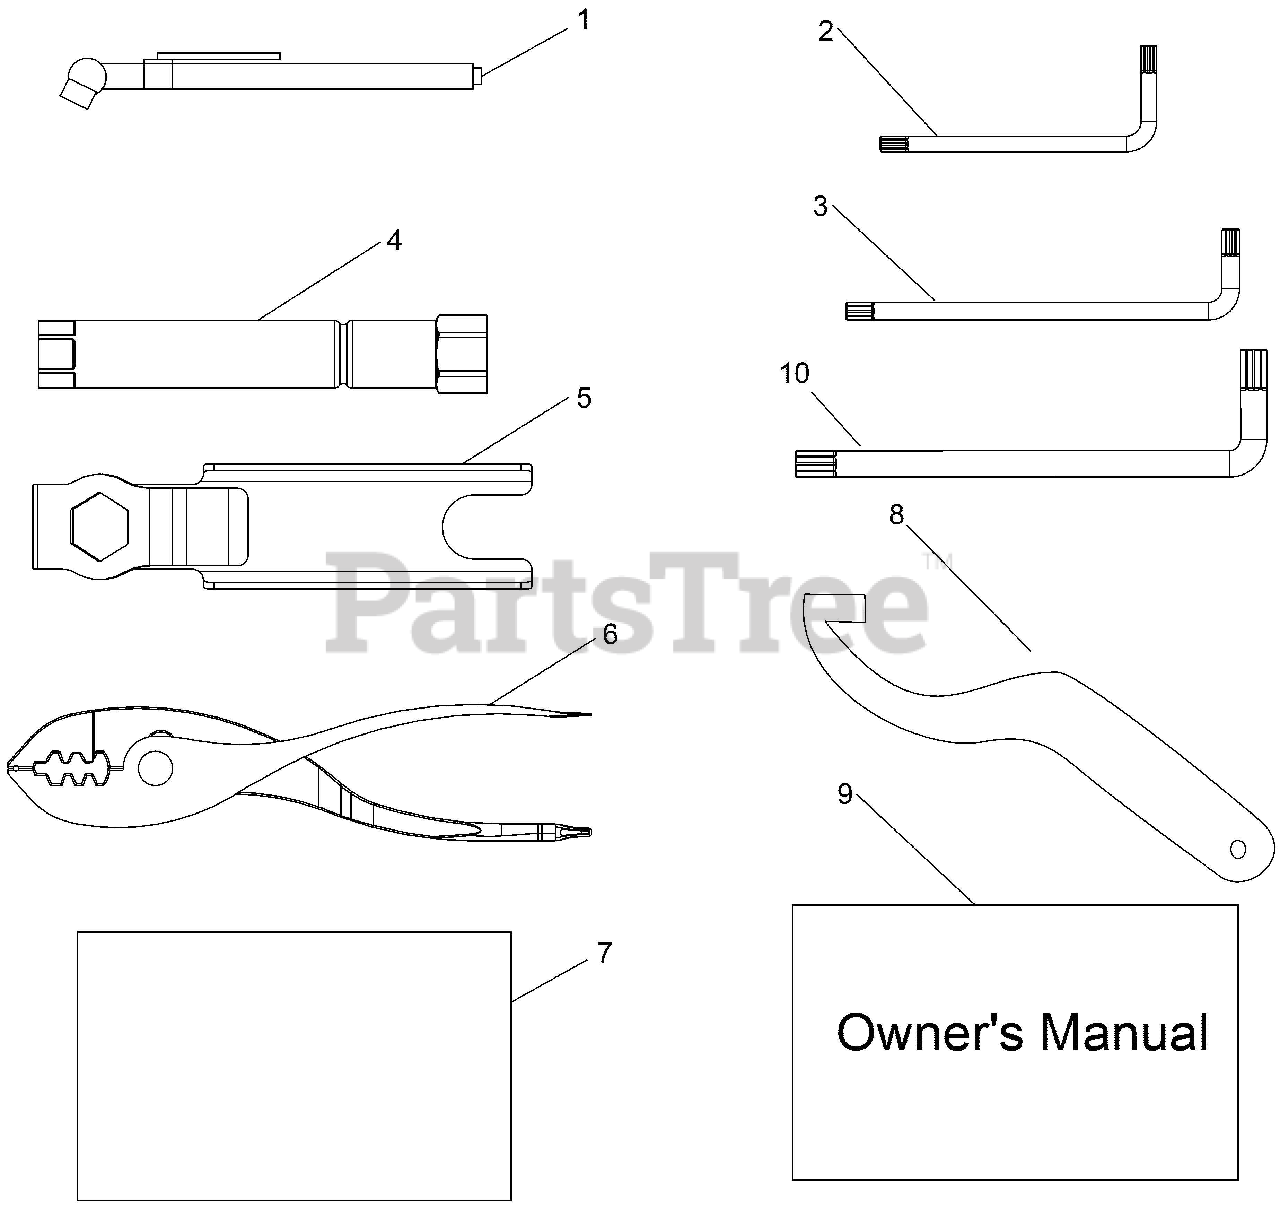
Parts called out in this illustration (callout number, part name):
1	GAUGE-TIRE PRESSURE,30 PSI
2	WRENCH-TORX,T-25
3	WRENCH-TORX,T-27
4	SOCKET, SPARK PLUG
5	HANDLE, SPARK PLUG
6	PLIERS-COMBO, #2 ASSEMBLY
7	POUCH,TOOLKIT,9"
8	WRENCH-SPANNER, CAM
9	MANUAL,GAS OWNERS -ENGLISH
10	WRENCH-TORX,T-40
